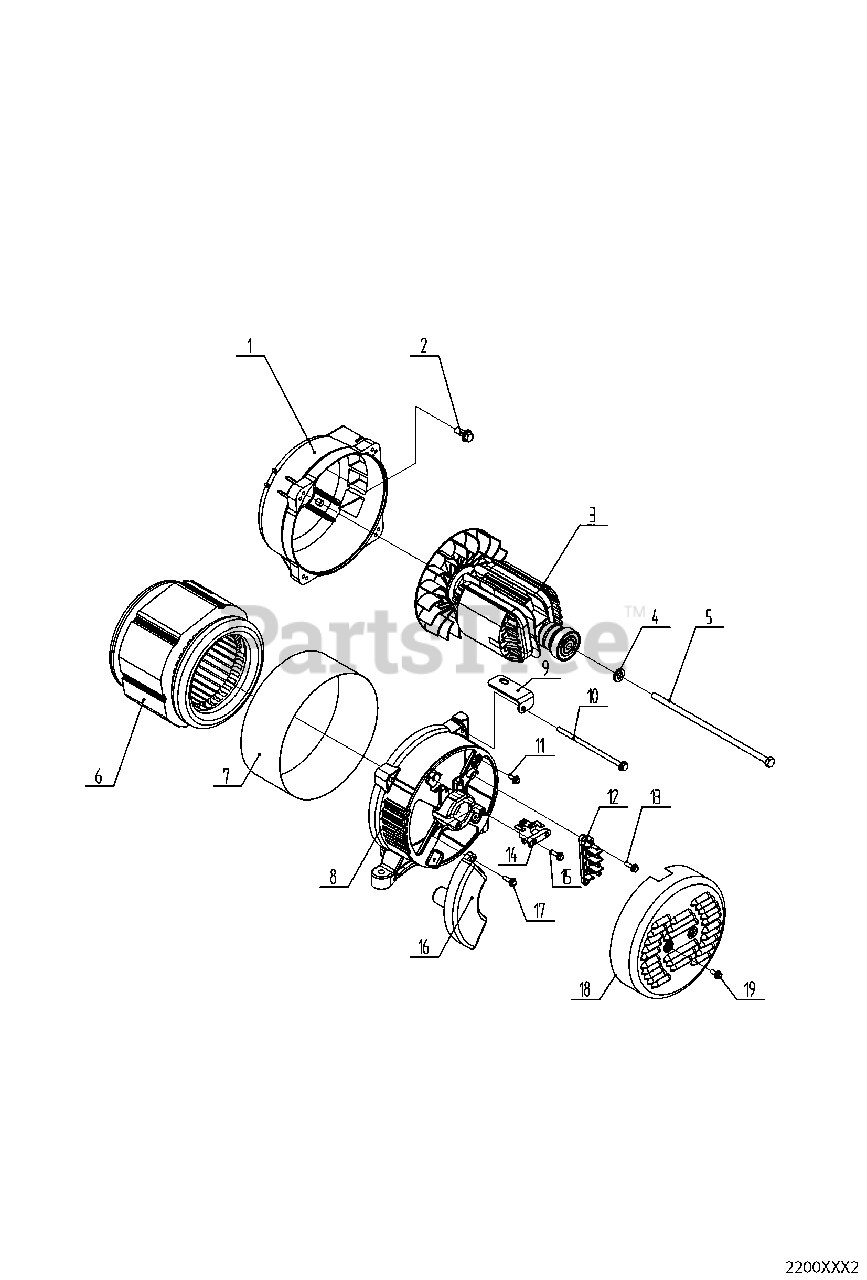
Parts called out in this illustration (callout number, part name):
2	FLANGE BOLT, M8X20
9	MUFFLER BRACKET
10	FLANGE BOLT, M6X130
11	FLANGE BOLT, M5X12
12	WIRING BOARD AY
19	FLANGE BOLT, M5X12
